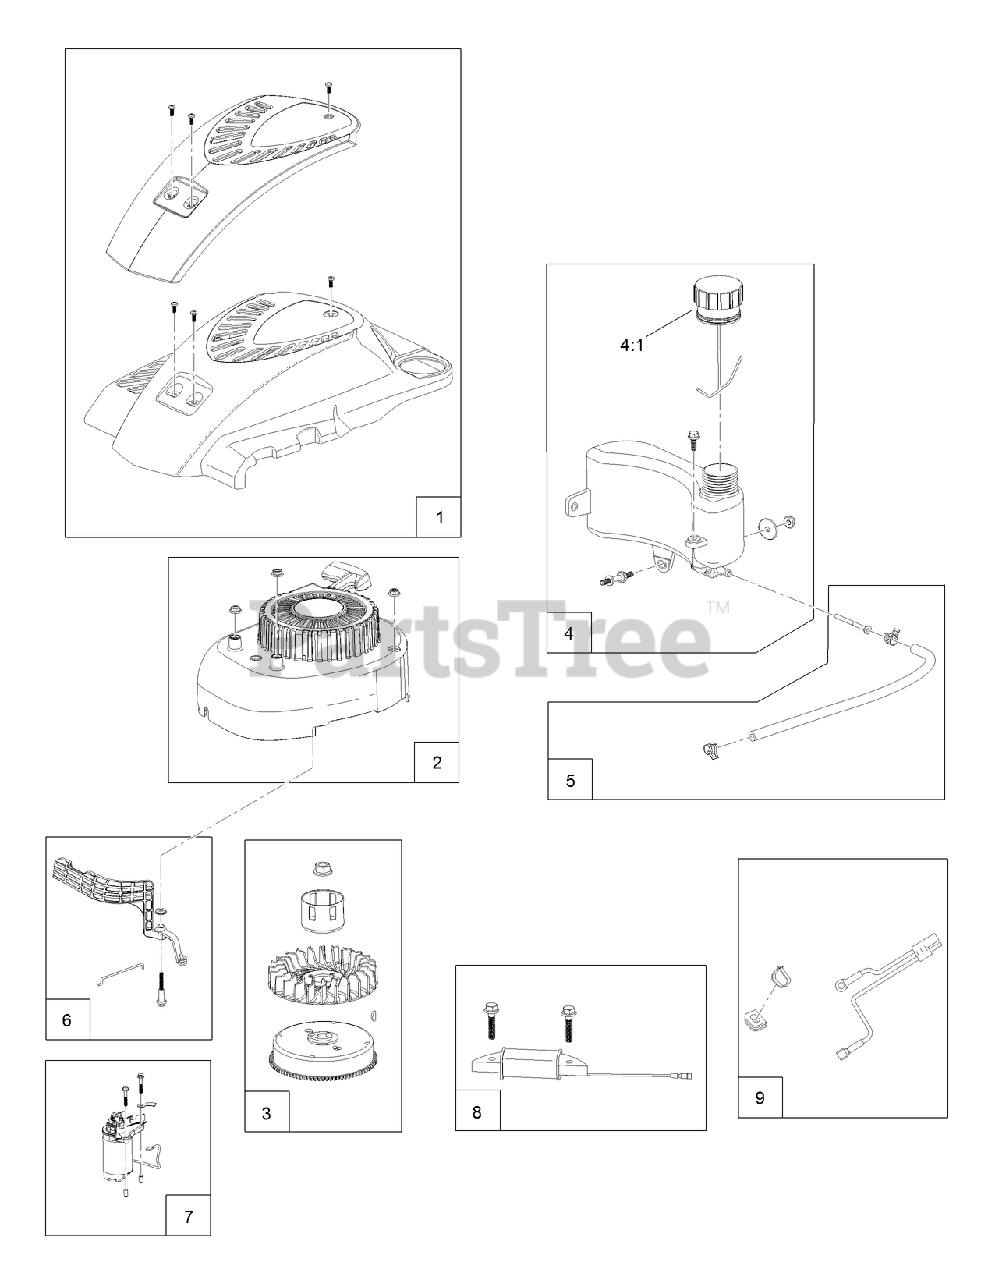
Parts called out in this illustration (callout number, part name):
1	SHROUD ASM
2	RECOIL AND BLOWER SHROUD KIT
3	FLYWHEEL AND FAN KIT
4	FUEL TANK KIT
4:1	CAP-FUEL
5	FUEL LINE KIT
6	AIR VANE KIT
7	STARTER ASM
8	ALTERNATOR ASM
9	WIRE HARNESS KIT
